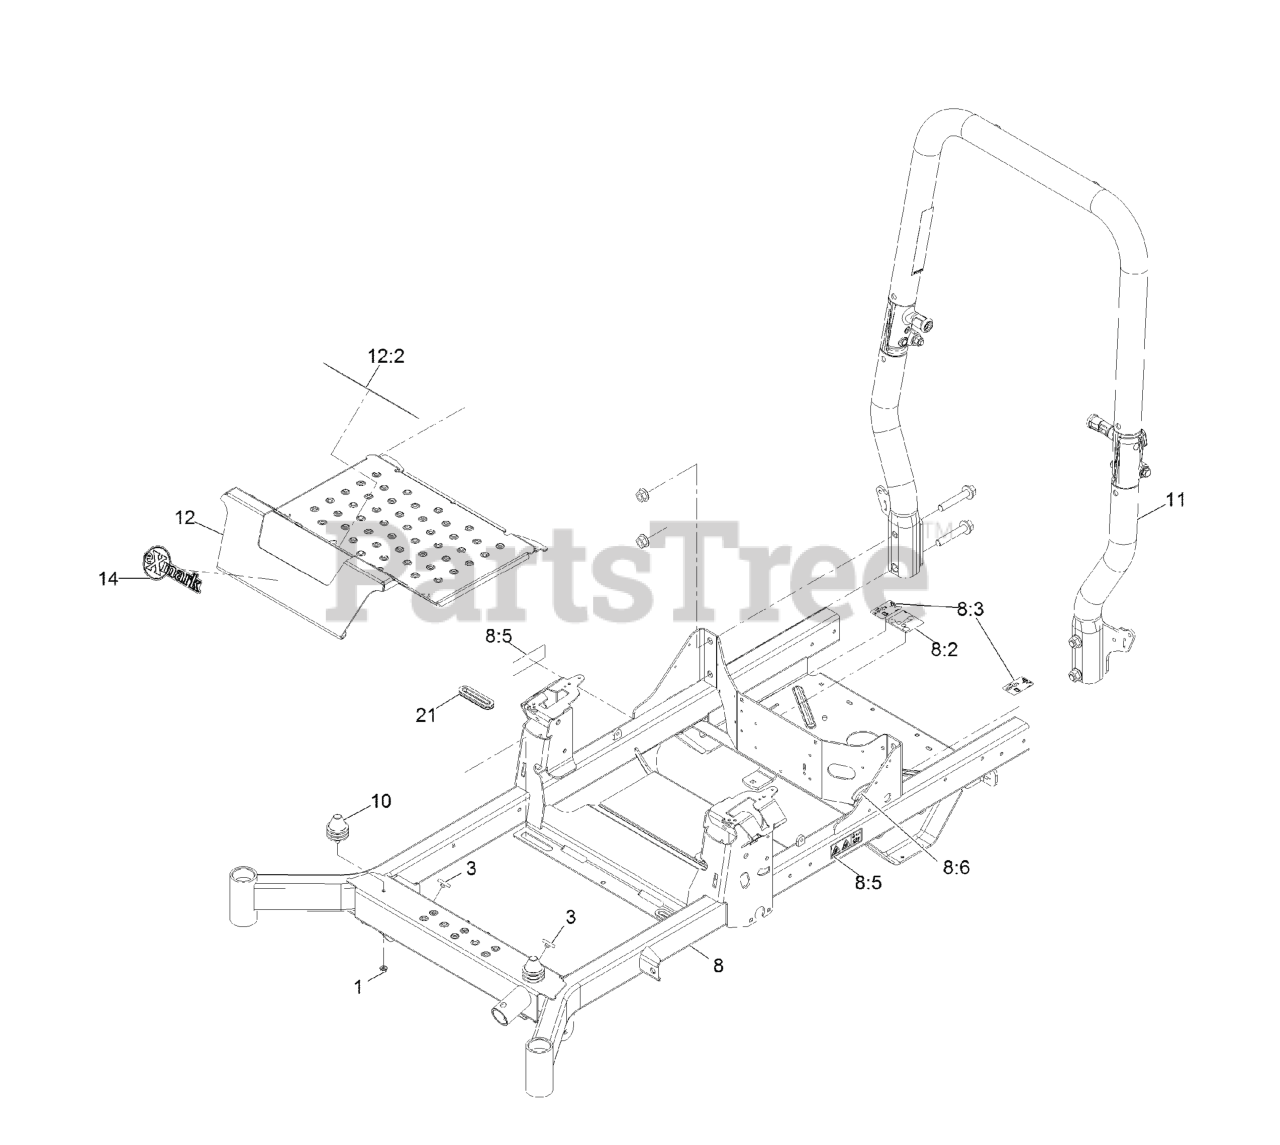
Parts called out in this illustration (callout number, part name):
1	NUT-HF, NI
3	BUMPER-PUSH-IN, RUBBER
8	FRAME ASM
8:2	DECAL-ROUTING, BELT
8:3	DECAL-RELEASE, DRIVE
8:5	DECAL-WARNING
8:6	STRIP-SEAL
10	ISOLATOR
11	ASM-ROPS TAPERED
12	PAN-FLOOR
12:2	DECAL-DANGER
14	DECAL-EXMARK LOGO
21	GROMMET-RUBBER
